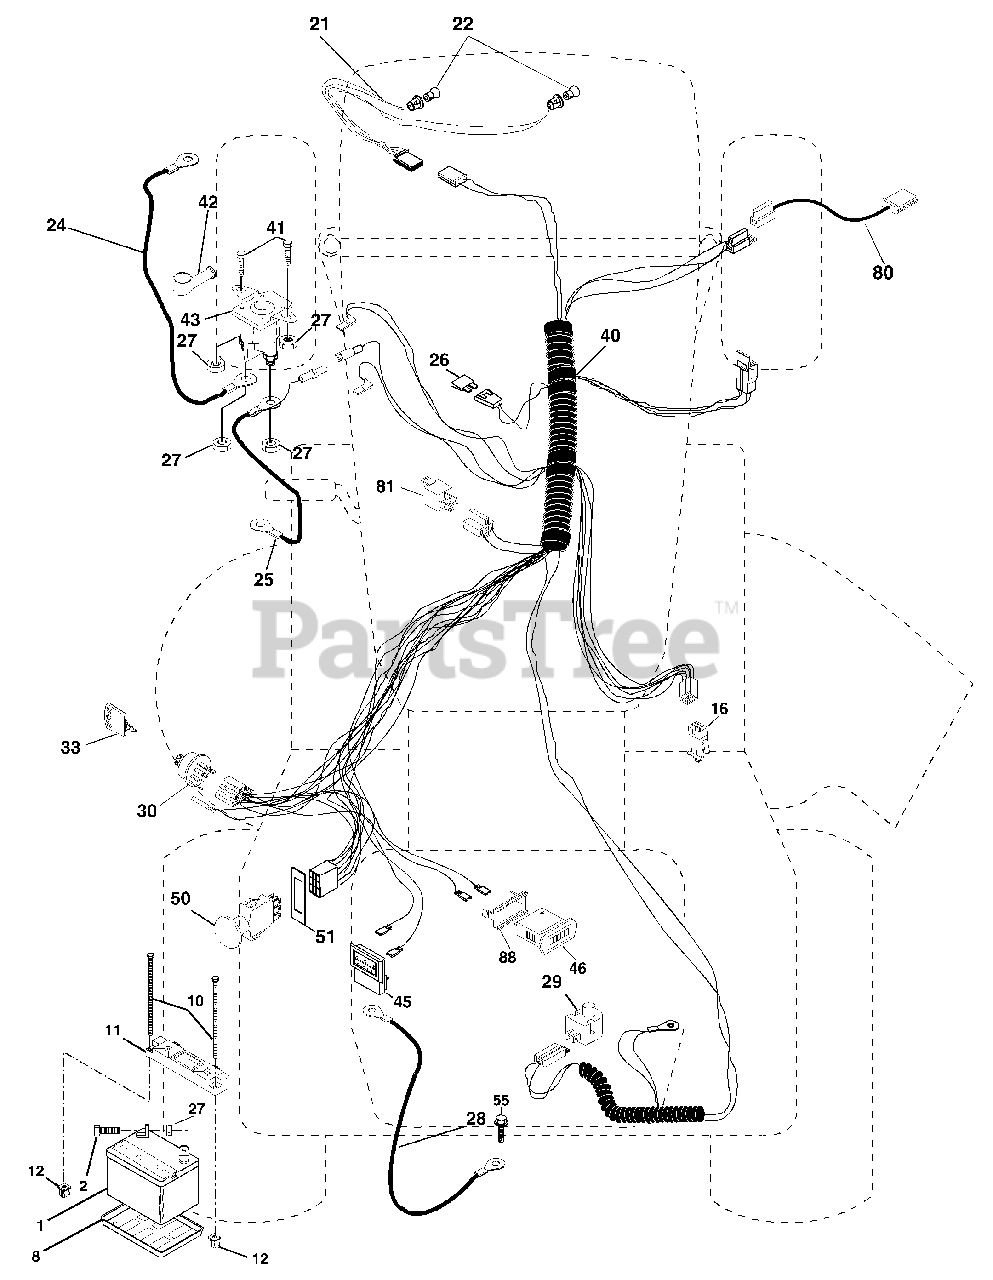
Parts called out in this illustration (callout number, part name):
1	Battery 12 Volt 25 AMP
2	Bolt Hex Hd 1/4-20unc X 3/4
8	Tray Battery
10	Bolt Brt Frt 1/4-20 x 75 Ainc
11	Holddown Battery Front Mount
12	Nut Push Nylon 1/4" Battery Frt
16	Switch Interlock Push-In
21	Harness Asm Light W/4152j
22	Bulb Light #1156
24	Cable Battery 6 Ga 22" red w/16 wire
25	Cable Battery 6 Ga 11" red
27	Nut Keps Hex 1/4-20 Unc
28	Cable Ground 6 Ga 21" black
29	Switch Plunger Nc Gray
30	Switch Ign
33	Key Ign Molded Generic
40	Harness Ign.
41	Bolt Blk Fin Hex 1/4 - 20 x 1/2
42	Cover Terminal Red
43	Solenoid
45	Ammeter Rectangular 15 Amp
46	Meter Hour
50	Switch PTO
51	Ring Retainer PTO
55	Screw Thdrol 5/16-18 x 1-1/2 Tyt
80	Harness Clutch Evx
81	Relay Asm.
89	Bracket Snap-In Hourmeter
